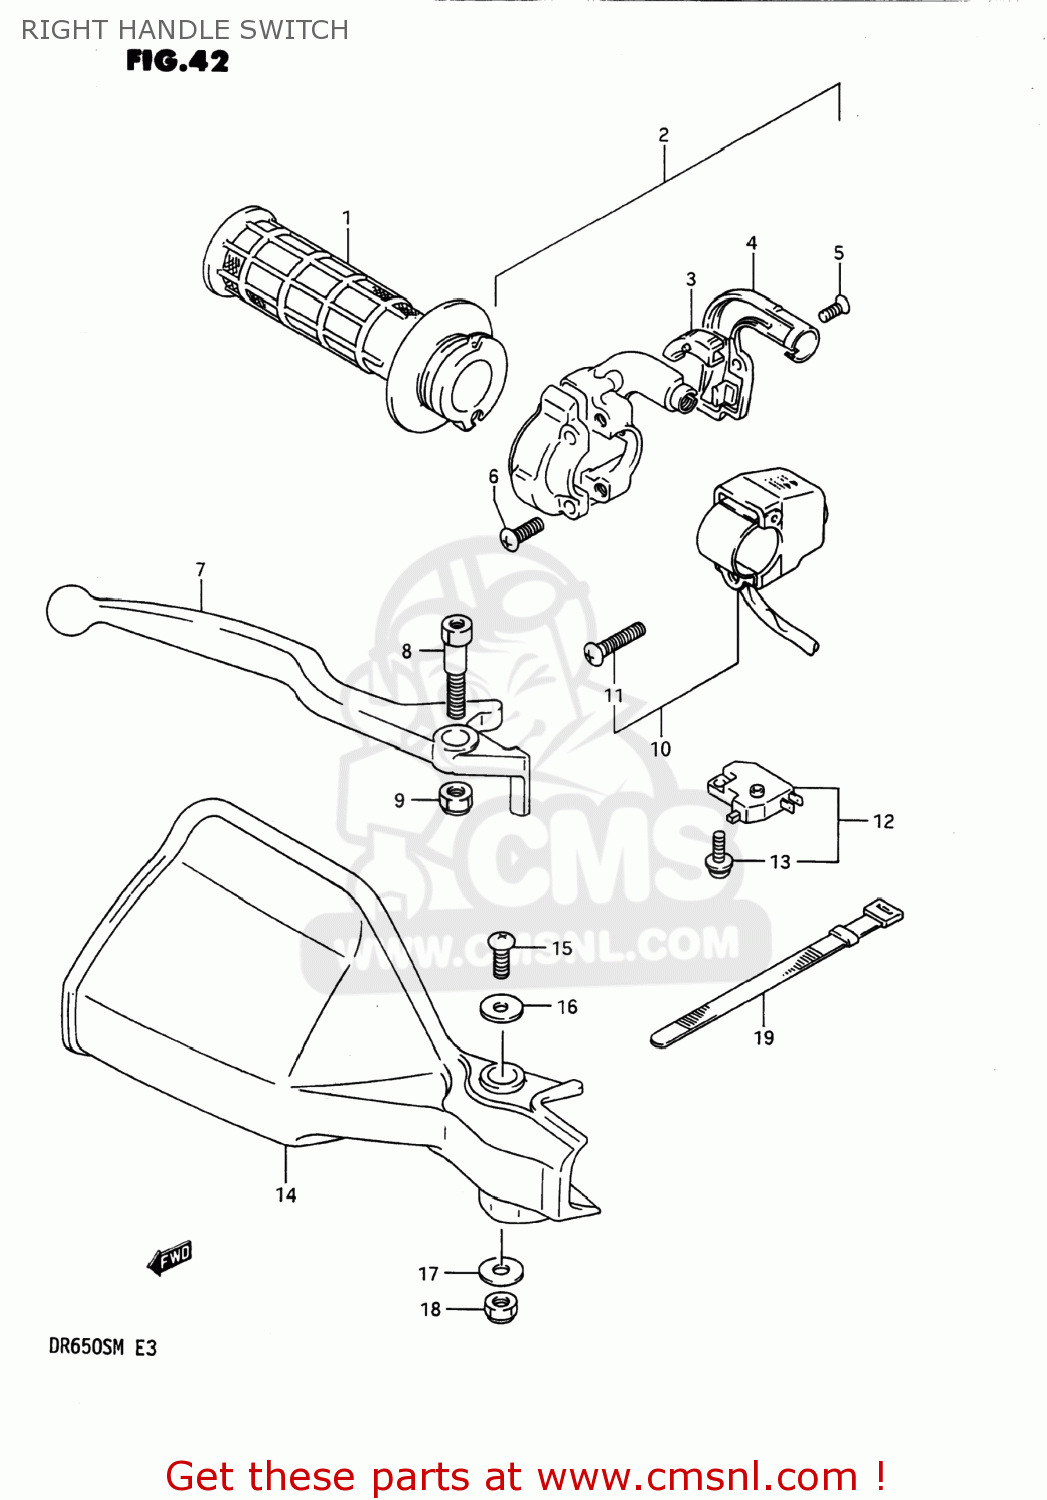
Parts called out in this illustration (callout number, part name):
1	GRIP,THROTTLE
2	CASE ASSEMBLY,THROTTLE
3	GUIDE PIECE,THROTTLE
4	COVER,THROTTLE CASE
5	SCREW 4X10
6	SCREW
7	LEVER,BRAKE
8	BOLT,BRAKE LEVER PIVOT
9	NUT 6MM
10	SWITCH ASSEMBLY,HANDLE,RIGHT
11	SCREW
12	SWITCH ASSEMBLY,STOP
13	SCREW
14	COVER,KNUCKLE,R
15	SCREW(5X10)
16	WASHER (5.5X16X1.2)
17	WASHER (6.5X17X1.6)
18	NUT 6MM
19	CLAMP(L:120)
